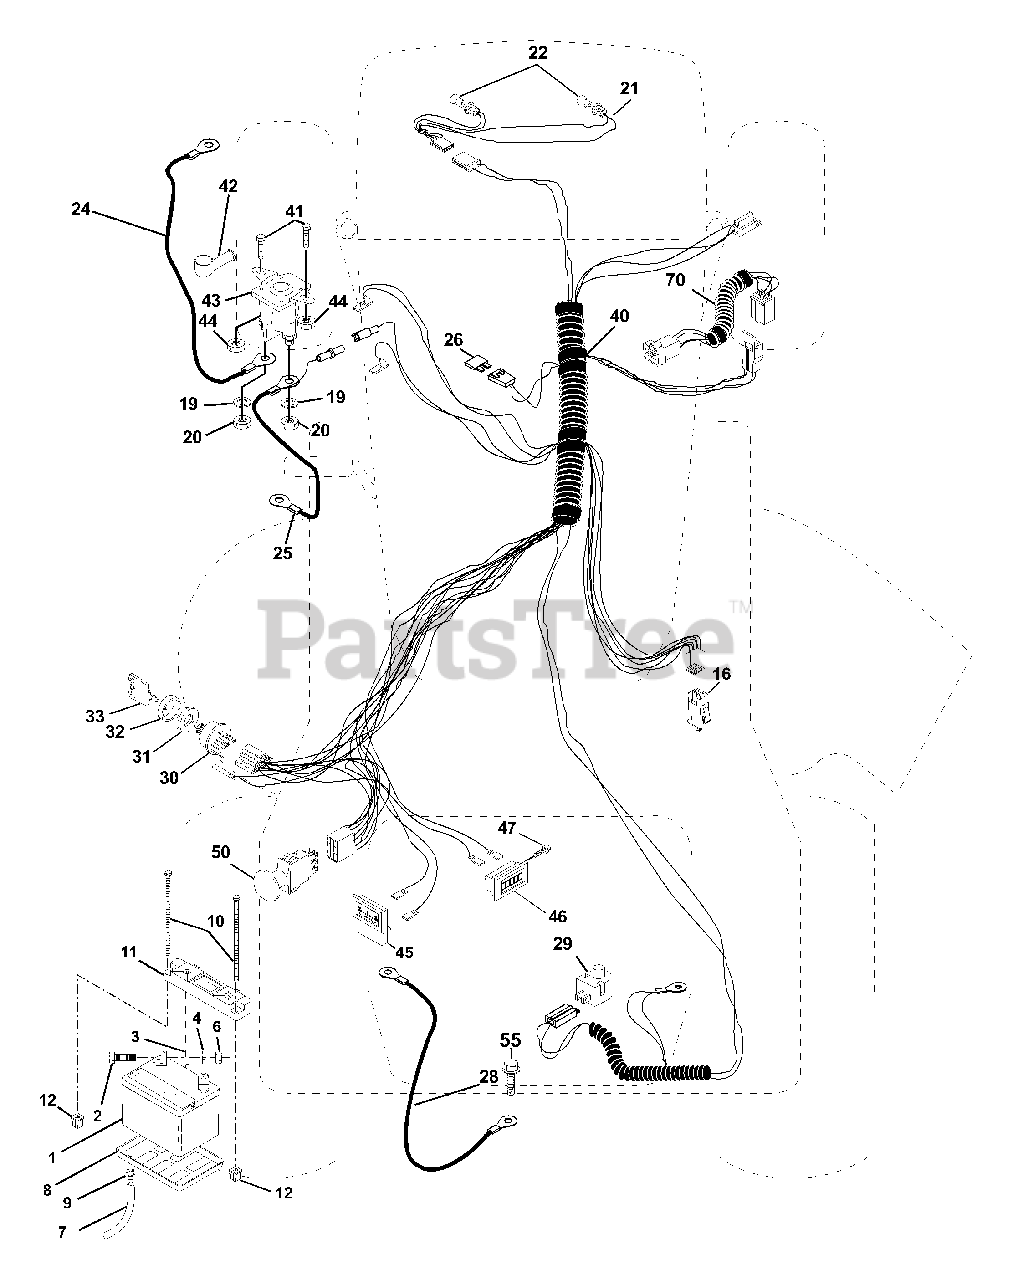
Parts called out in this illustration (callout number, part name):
1	Battery 12 Volt 35 AMP
2	Bolt Hex Hd 1/4-20unc X 3/4
3	Washer 9/32 X 5/8 X 16 Ga.
4	Washer Lock Hvy Helical 1/4
6	Nut Fin Hex 1/4-20 Unc
7	Tube Plastic 46"Front Battery
8	Tray Battery 7.80 x 5.25 Blk
9	Clamp Hose Olive
10	Bolt Btr. Frt. 1/4-20 x 7.5 Zinc
11	Holddown Battery Front Mount
12	Nut Push Nylon 1/4" Battery Frt.
16	Switch Interlock Push-In
19	Washer Lock 1/4
20	Nut Jam Hex 1/4-20 Unc
21	Harness Asm Light W/4152j
22	Bulb Light #1156
24	Cable Battery 6 Ga 11" red
25	Cable Battery 6 Ga 22" red w/16 wire
26	Fuse 30 AMP Auto Green
28	Cable Ground 6 Ga 21" black
29	Switch Plunger Nc Gray
30	Switch Ign 4 pos w/lights
31	Nut Ignition
32	Cover Sw Ignition
33	Key Ign Modelled Generic
40	Harness Ign.
41	Bolt Blk Fin Hex 1/4 - 20 x 1/2
42	Cover Terminal Red
43	Solenoid
44	Nut Keps Hex 1/4-20 Unc
45	Ammeter Rectangular 15amp
46	Meter Hour
47	Screw 10-24 x 1/2 Black
50	Switch PTO 3PDT Black Delta 96
55	Screw Thdrol 5/16-18 x 1/2 TYT
70	Harness, Eng. Kohler CV 11 1Pc/PL
